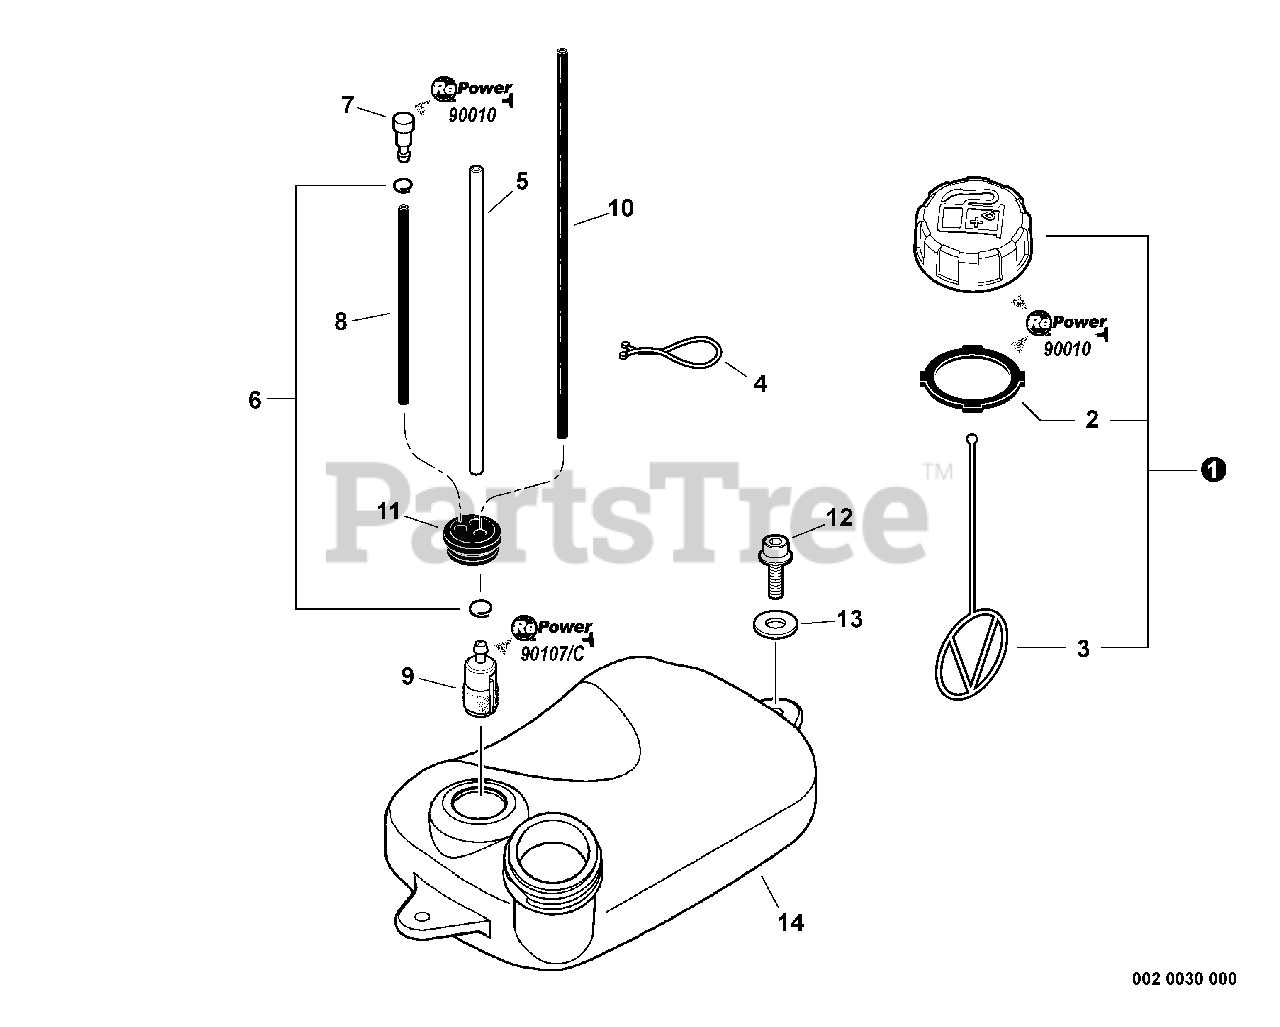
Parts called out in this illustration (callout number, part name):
1	CAP ASSY - ORANGE
2	GASKET, CAP
3	CONNECTOR, CAP
5	PIPE - 3X6X125 -- CLEAR
6	CLIP - 6
7	VENT, FUEL TANK
8	PIPE - 3X5X70 -- BLACK
9	FILTER, FUEL
10	PIPE - 3X5X210 -- BLACK
11	GROMMET
12	SCREW - 5X20
13	WASHER - 5
14	TANK, FUEL
15	RePower TUNE-UP KIT
16	Repower CAP AND VENT KIT
